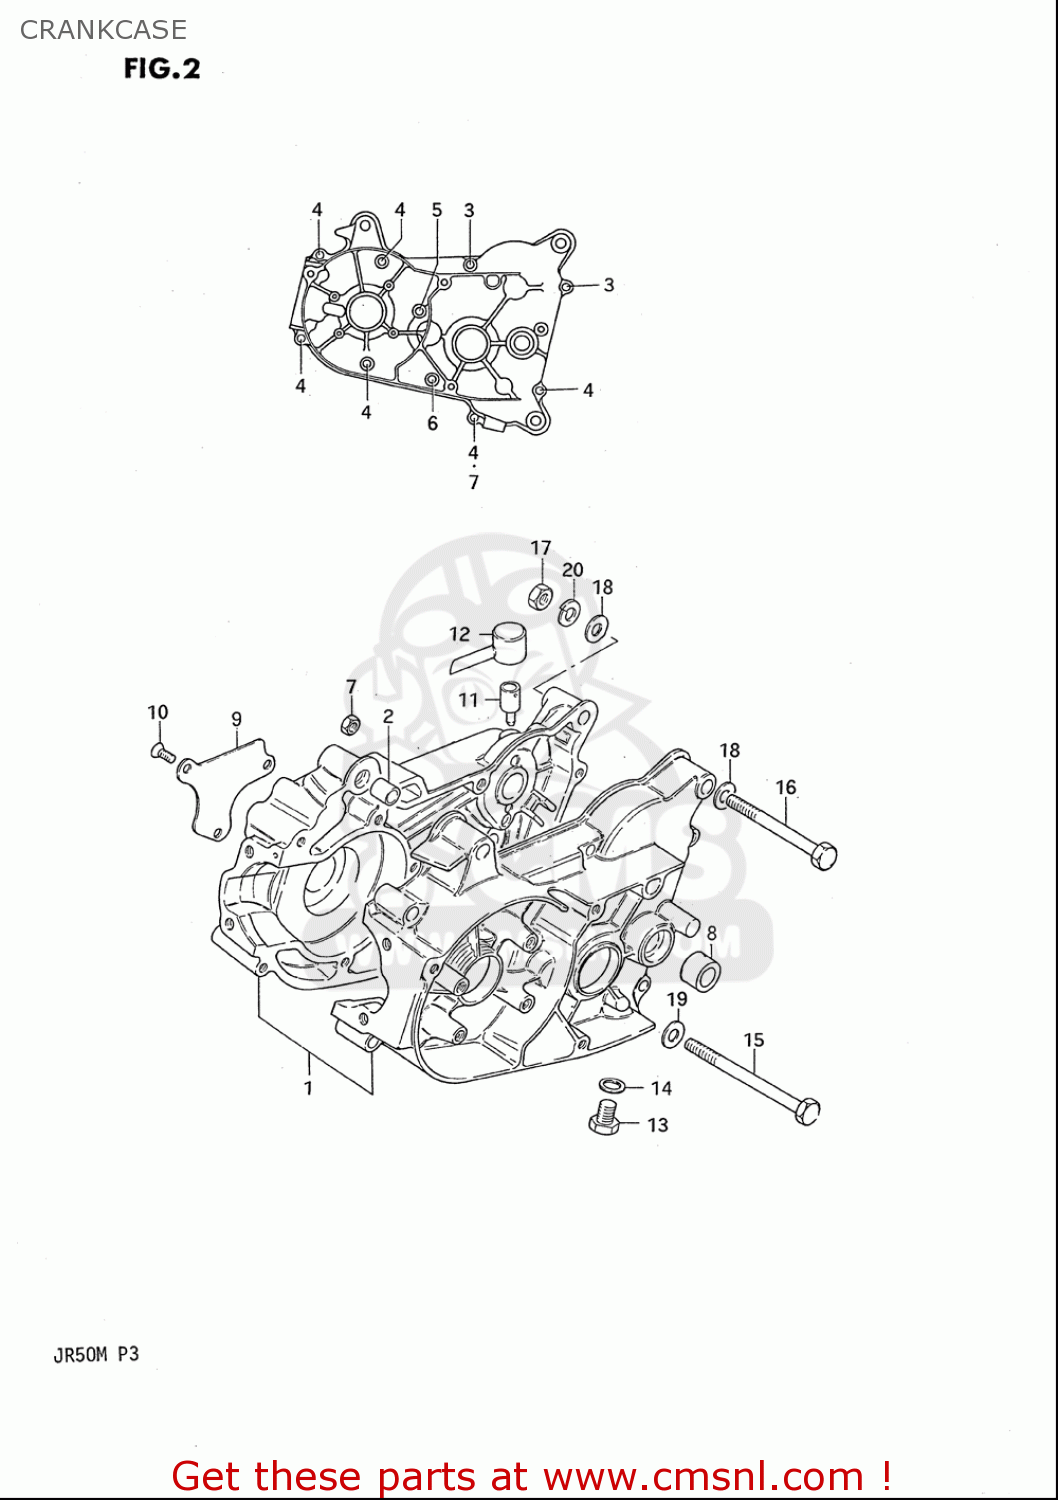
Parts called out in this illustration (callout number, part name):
1	CRANKCASE SET
2	PIN
3	SCREW
4	SCREW
5	SCREW
6	SCREW
7	NUT
8	BUSH
9	PLATE,OIL RESERVOIR
10	SCREW
11	PLUG,T/M BREATHER
12	GASKET (NAS)
13	PLUG
14	GASKET(10X14X3.6) (NAS)
15	BOLT
16	BOLT
17	NUT
18	WASHER
19	WASHER (8.2X22X3.2)
20	WASHER,LOCK
